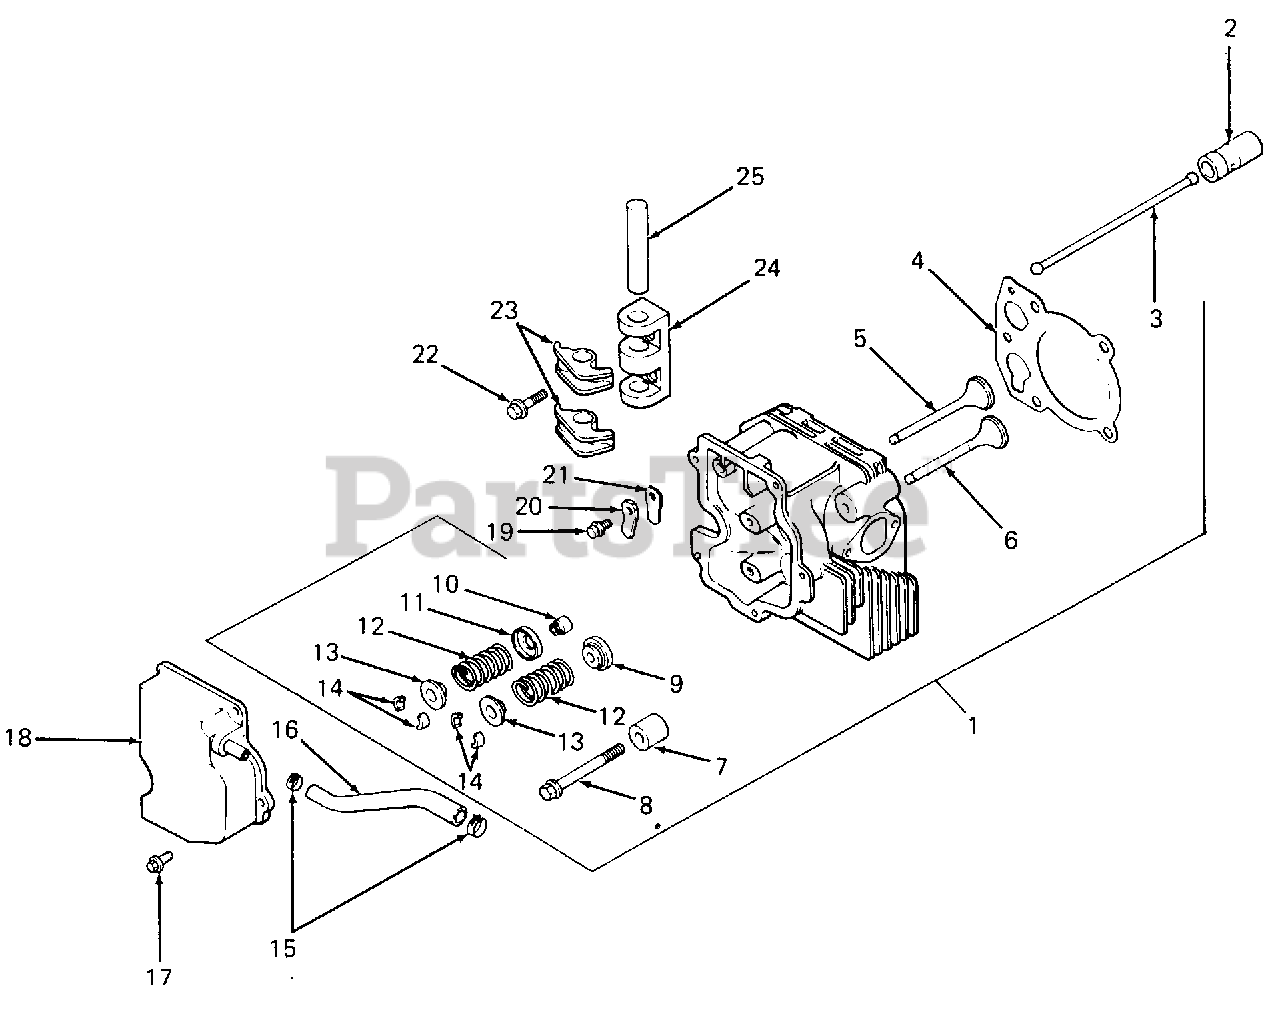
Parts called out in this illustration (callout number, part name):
1	Kit, Cylinder Head
2	Lifter, Valve
3	Rod, Push
4	Gasket, Cylinder Head
5	Valve, Intake, Std
6	Valve, Exhaust, Std
7	Spacer, Head Bolt Exhaust Port
8	Screw, Cylinder Head M10 X 1.5 X 80
9	Rotator, Exhaust Valve
10	Seal, Valve Stem
11	Retainer, Spring
12	Spring, Valve
13	Cap, Valve Spring
14	Kit, Retainer
15	Clamp, Hose
16	Hose, Breather
17	Screw, Valve Cover, M6 X 1.0 X 20
18	Cover, Valve w/Nipple
19	Screw, Breather Reed Retainer, M5 X 0.8 X 10
20	Retainer, Breather Reed
21	Reed, Breather
22	Screw, Rocker Bridge, M6 X 1.0 X 25
24	Bridge, Rocker Arm
25	Shaft, Rocker Arm
